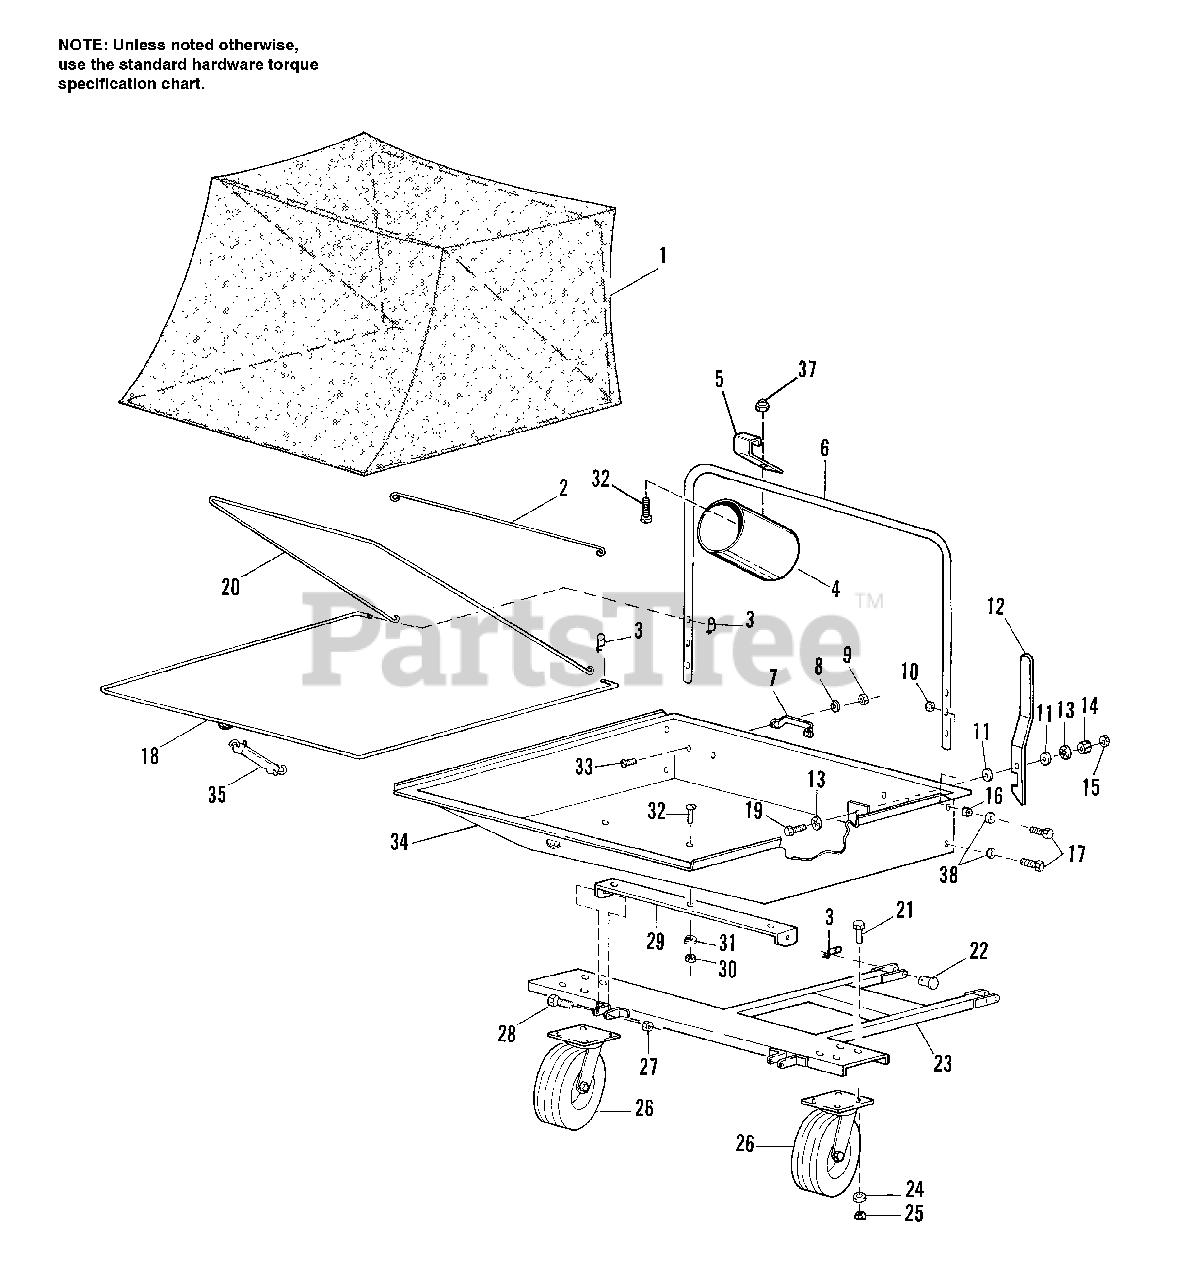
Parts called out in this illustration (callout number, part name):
2	ROD, Straight
3	CLIP, Hairpin Safety
4	SLEEVE, Plastic Connecting
5	CLAMP, Sleeve
6	TUBE, Support
7	HANDLE, Lift
8	WASHER, Lock, 1/4
9	NUT, Hex, 1/4-20
10	NUT, Hex Lock, 5/16-18
11	WASHER, 5/16
12	HANDLE, Latch
13	WASHER, Spring, 5/16
14	NUT, Hex, 5/16-18
15	NUT, Hex Jam, 5/16-18
16	SPACER, Plastic, 5/16
17	CAPSCREW, Hex Hd, 5/16-18 x 1-1/2
19	CAPSCREW, Hex Hd, 5/16-18 x 1-1/4
20	ROD, Support
21	CAPSCREW, Hex Hd, 3/8-16 x 1
22	PIN, 1/2 x 1-1/4
24	WASHER, 3/8
25	NUT, Hex Lock, 3/8-16
26	WHEEL, Swivel, 410/350-4
27	NUT, Lock, 1/2-13
28	CAPSCREW, Hex Hd, 1/2-13 x 1-1/4
29	"U" BRACKET
30	NUT, Hex, 5/16-18
31	WASHER, Lock, 5/16
32	BOLT, Slotted Truss Hd, 5/16-18 x 3/4
33	CAPSCREW, Hex Hd, 1/4-20 x 1/2
35	STRAP, Rubber, 6"
37	NUT, Hex Nylon Lock, 1/4-20
38	WASHER, 5/16
